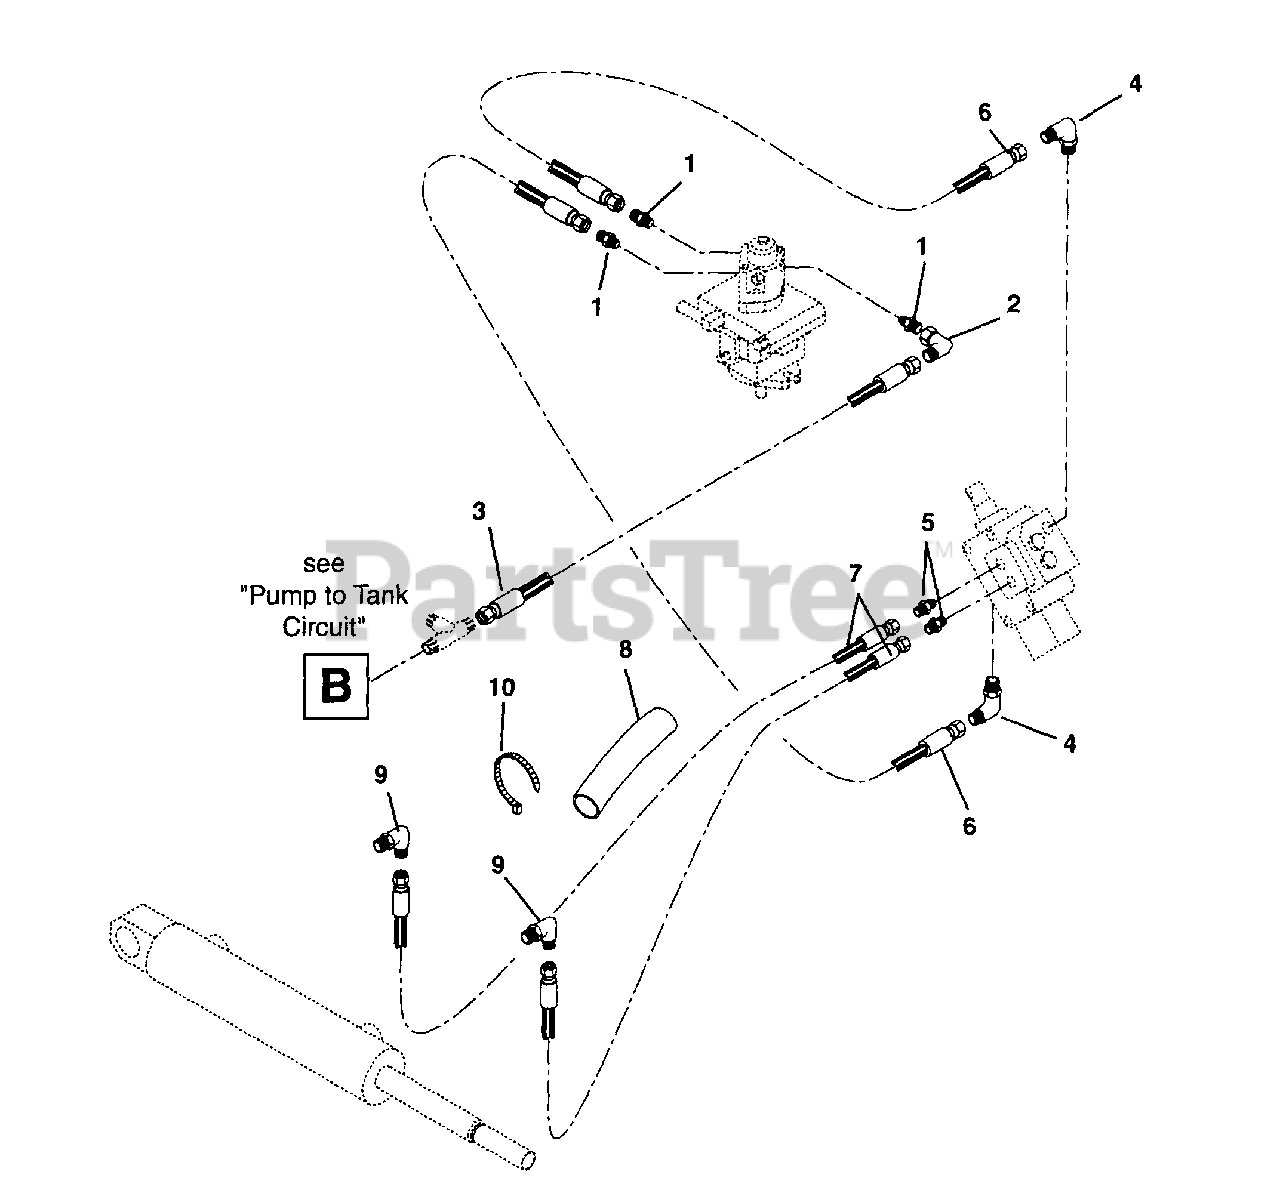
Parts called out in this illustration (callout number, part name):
1	ADP 0503-4-6
2	ADPT 3903-6-6
3	HOSE,HYD VALVE TO TANK
4	ADPT 2503-6-6
5	ADPT 0503-4-4
6	HOSE HYDRAULIC 3/8 27.75 LONG
7	HOSE-HYDRAULIC 1/4 40.5" LONG
8	SLEEVE, PROTECTIVE
9	ADPT 2503-4-4
10	CABLE TIE LG 5-1/2
